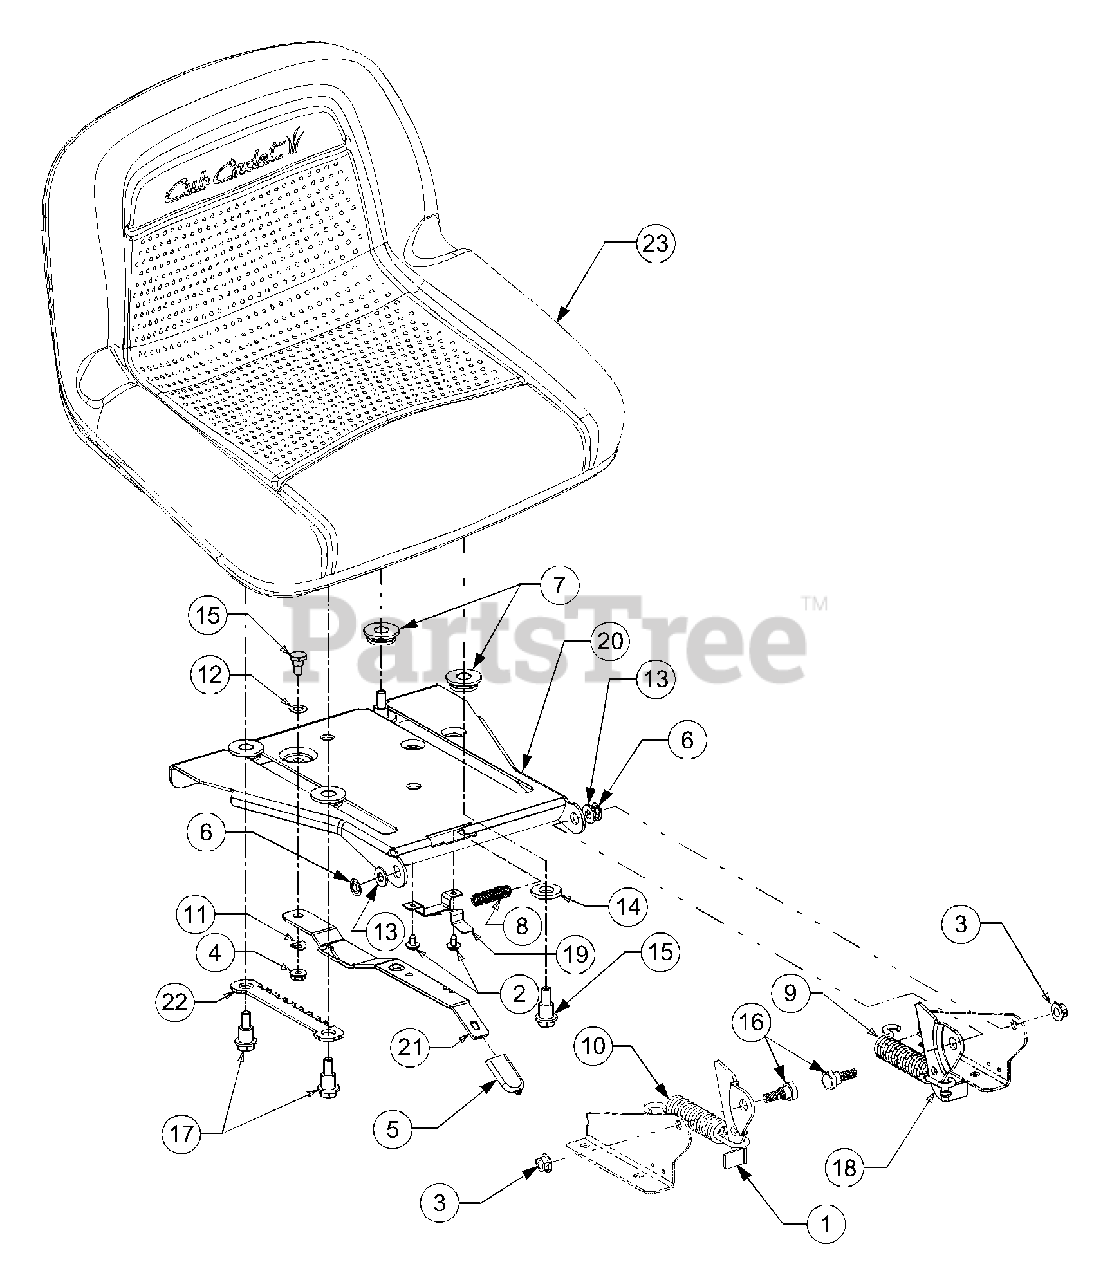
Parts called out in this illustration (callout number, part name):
1	Bracket, Seat Lift
2	Screw, #10-16, 0.375
3	Nut, Flange Lock, 5/16-18, Gr5
4	Nut, Flange Lock, 1/4-20
5	Grip, Seat, Adjustment (Yellow)
6	Nut, Speed, .3125 ID
7	Spacer, Seat, Adjustment
8	Spring, Compression .41 OD x 1.50
9	Spring, Extension, .80 Dia x 4.2 Lg.
10	Spring, Extension, .815 Dia x 4.4 Lg.
11	Washer, Spring, .265 x .562 x.025
12	Washer, Flat, .344 ID x .62 OD
13	Washer, Flat, .344 x .688 x .065
14	Washer, Flat, .531 x 1.062 x .134
15	Screw, Shoulder, .340 x .285, 1/4-20
16	Shoulder, Screw .437 x .286 Lg
17	Screw, Shoulder, .50 x.50, 5/16-18
18	Bracket, Seat Lift
19	Stop, Seat, Adjustment
22	Selector, Seat, Adjustment
23	Seat, Mid-back, V-1480
